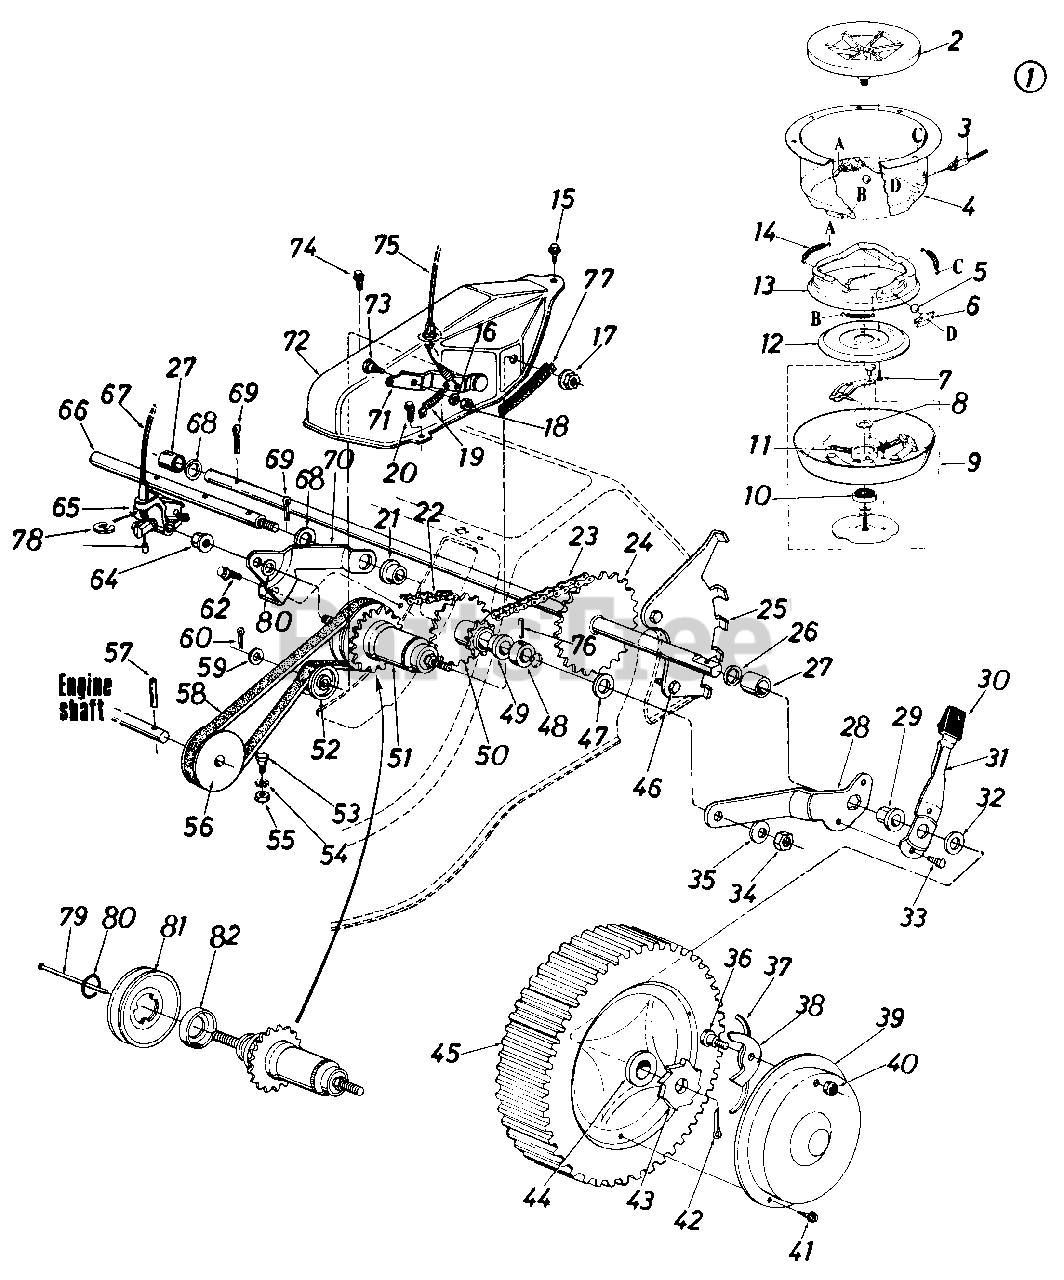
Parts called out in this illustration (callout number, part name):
1	Blade/Brake Clutch Ass'y.
3	BBC-Clutch Cable 46"
4	Clutch Housing
5	Steel Ball .500" Dia.
7	Hex Wash. TT-Tap Cl-Scr. 1/4-20 x .75" Lg.
8	Fl-Wash. .690" I.D. x 1.060" O.D.
9	Clutch Blade Hsg. Ass'y.
10	Ball Brg. .669" I.D. x 1.574" O.D.
11	Compression Spring .32" O.D. x 2.00" Lg.
12	Clutching Cone
13	Brake Cup Cone
14	Extension Spring 1.75" Lg.
15	Hex Drilling Scr. #10 x .50"
16	L-Wash. 1/4" I.D.
17	Hex Nut 3/8-24 Thd.
18	Hex Nut 1/4-20 Thd.
19	Extension Spring 1.12" Lg.
20	Hex Wash. S-Tap Scr. 1/4-20 x .50" Lg.
21	Flg. Brg. 506" l.D. Plastic
22	#48 Chain 1/2" Pitch x 38 Links (Endless)
23	#48 Chain 1/2" Pitch x 32 Links (Endless)
24	Rear Shaft Ass'y. 20.75"
25	Index Plate Rear L.H.
26	Fl-Wash. .510" I.D. x 1.0"
27	Spacer.740" I.D.
28	Pivot Brkt. L.H.
29	Hex Flange Brg. 506n l.D. Plastic
30	Spring Lever Knob
31	Spring Lever
32	Fl-Wash. .531" I.D. x .930"
33	Hex B-Tap Scr. 1/4 x .38"
34	Hex Jam Nut 3/8-16 Thd.
35	Bell-Wash. .400" I.D. x .88"
36	Shld. Bolt .342" Dia. x .268
37	Spring Nylon
38	Pawl
40	Hex Ins. L-Nut 1/4-20 Thd.
41	Pan Hd. Tap Scr. #12 x .50" Lg.
42	Cotter Pin 1/8n Dia. x 1.0"*
43	Ratchet Wheel 1.62" O.D.
44	Fl-Ball Brg. 1/2" l.D.
45	Wheel Ass'y. Comp. 8 x 1.75
46	Hex L-Wash. Hd. AB-Tap Scr. 1/4 x.62n Lg.
47	Bell-Wash. 40" l.D. x 1.13"
48	Spacer.505n l.D.
49	Flg. Brg. 506" l.D. Plastic
50	9 and 21 Tooth Sprocket Ass'y.
51	Shimano 3-Sp. Hub w/18 Tooth Sprocket
52	Fl-ldler Plastic 1.62" Dia.
53	Shld. Bolt .437" Dia. x .180
54	L-Wash. 5/16" l.D.
55	Hex Nut 5/16-18 Thd.
56	1/2" "V"-Engine Pulley .50" I.D. x 2.80" O.D.
57	Spring Pin Spir. 3/16" Dia. x 1.50" Lg.
59	Fl-Wash. 531" l.D. x ,930n
60	Cotter Pin 1/8n Dia. x 1.0"
62	Hex Wash. Hd. Tap Scr. 5/16-18 x ,75" Lg.
64	Hex Nut 3/8-24 Thd.
65	Shimano 3-Sp. Shift Bell Crank
66	Pulley Shaft 10" Lg.
67	Shimano 3-Sp. Solid Shift Cable
68	Fl-Wash. .531" I.D. x .930"
69	Cotter Pin 3/32" Dia. x 1.0
70	3-Sp. Hub Bracket
71	Idler Bracket Ass'y.
72	3-Sp. Belt Cover
73	Shld. Bolt .375" Dia. x .181
74	Hex TT-Tap Scr. 1/4-20 x .75" Lg.
75	S.P. Cable-53" Lg. Blue
76	Spring Pin Spir. 3/16n Dia. x 1 on Lg
78	Snap Ring
79	Shifting Pin
80	Pulley Snap Ring
81	3/2, V-Pulley 1.375" l.D. x 3.25" O.D.
82	Shimano 3-Sp. Dust Cover
